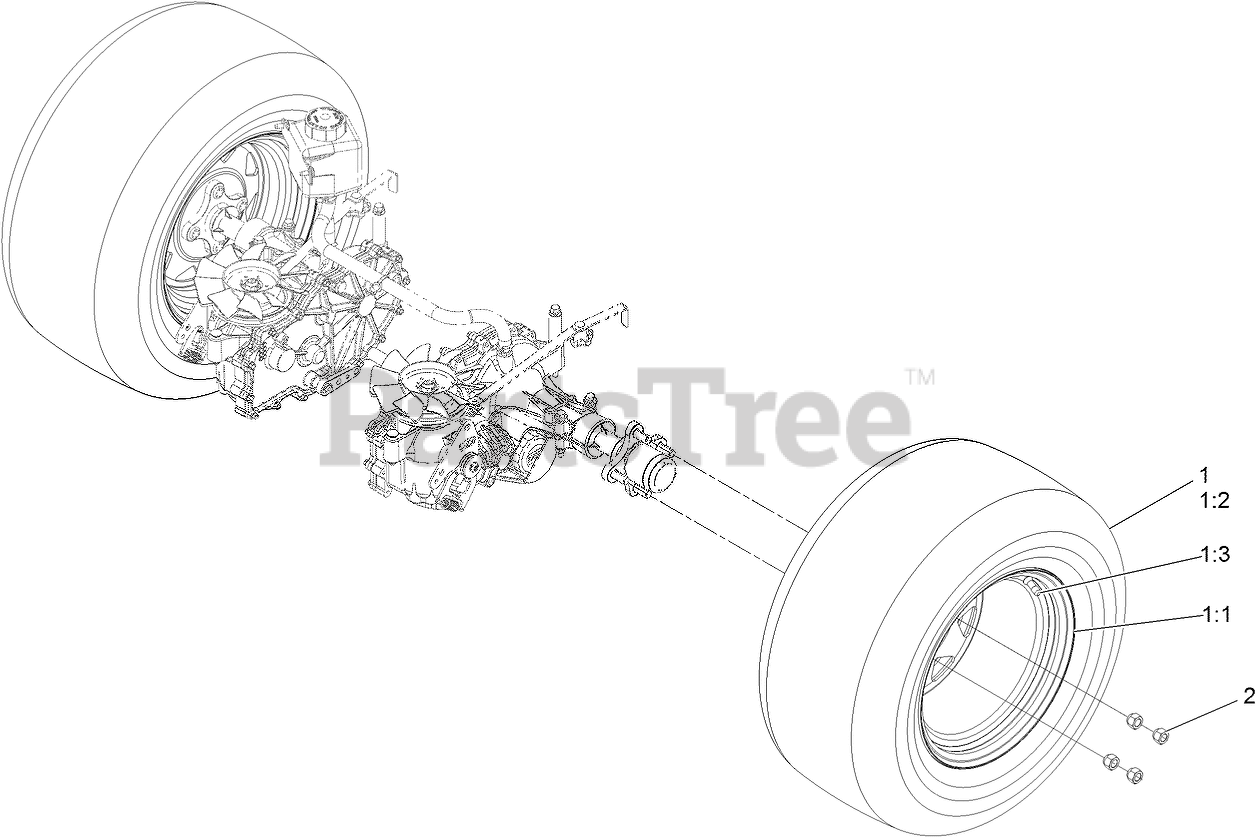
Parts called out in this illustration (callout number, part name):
1	WHEEL AND TIRE ASM
1:1	WHEEL RIM 12X8.5
1:2	TIRE
1:3	Stem-Valve
2	NUT-LUG
